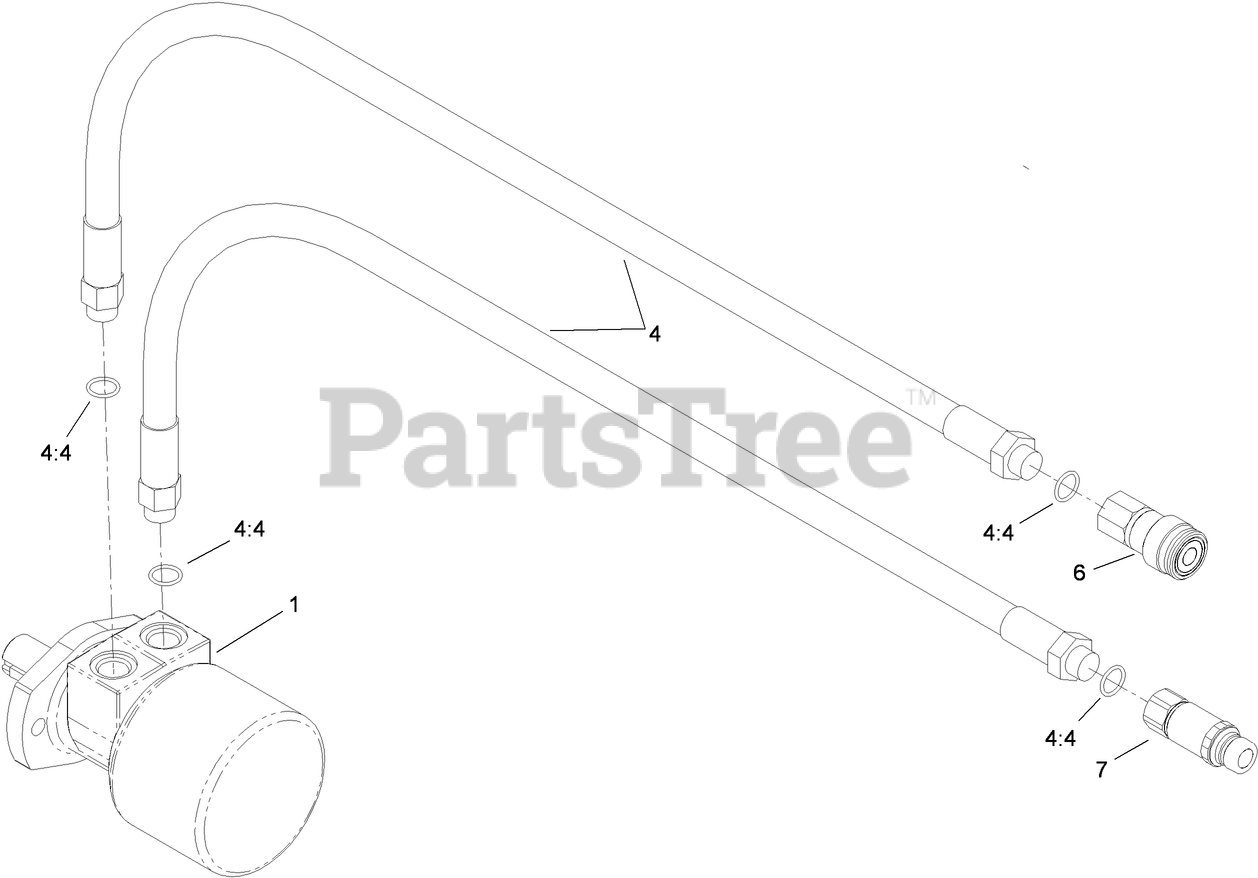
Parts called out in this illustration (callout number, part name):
1	MOTOR-HYDRAULIC
4	HOSE ASM
4:4	O-RING
6	COUPLER-FACE, FLUSH
7	NIPPLE-CONNECT, PRESSURE
